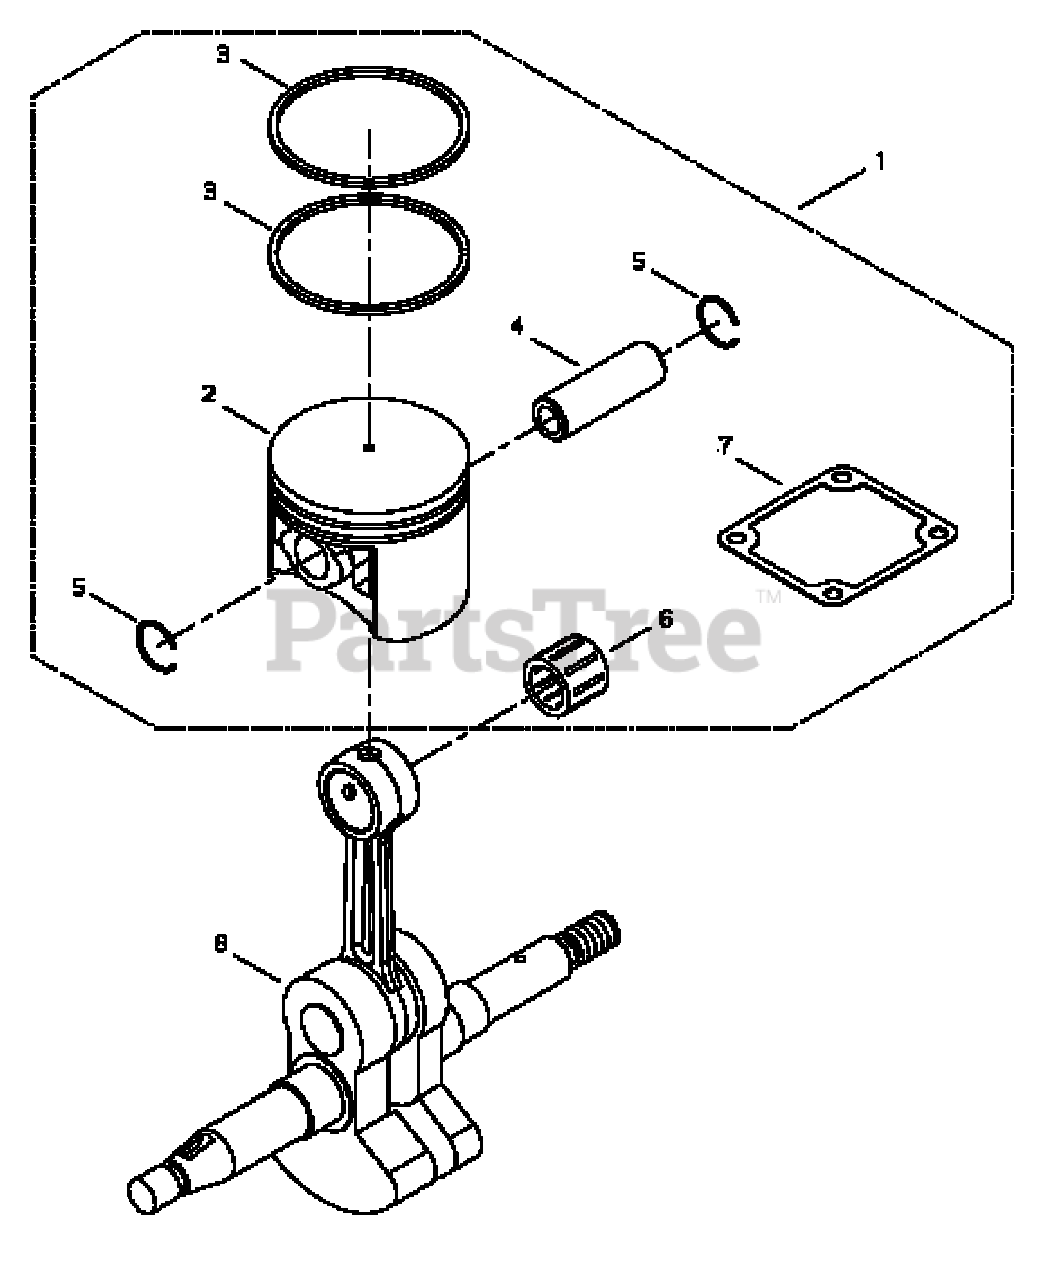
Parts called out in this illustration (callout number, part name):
1	PISTON SET
2	PISTON
3	RING, PISTON
4	PIN, PISTON
5	RING, RETAINING
6	BEARING, NEEDLE
7	GASKET, CYLINDER
8	CRANKSHAFT ASSY
